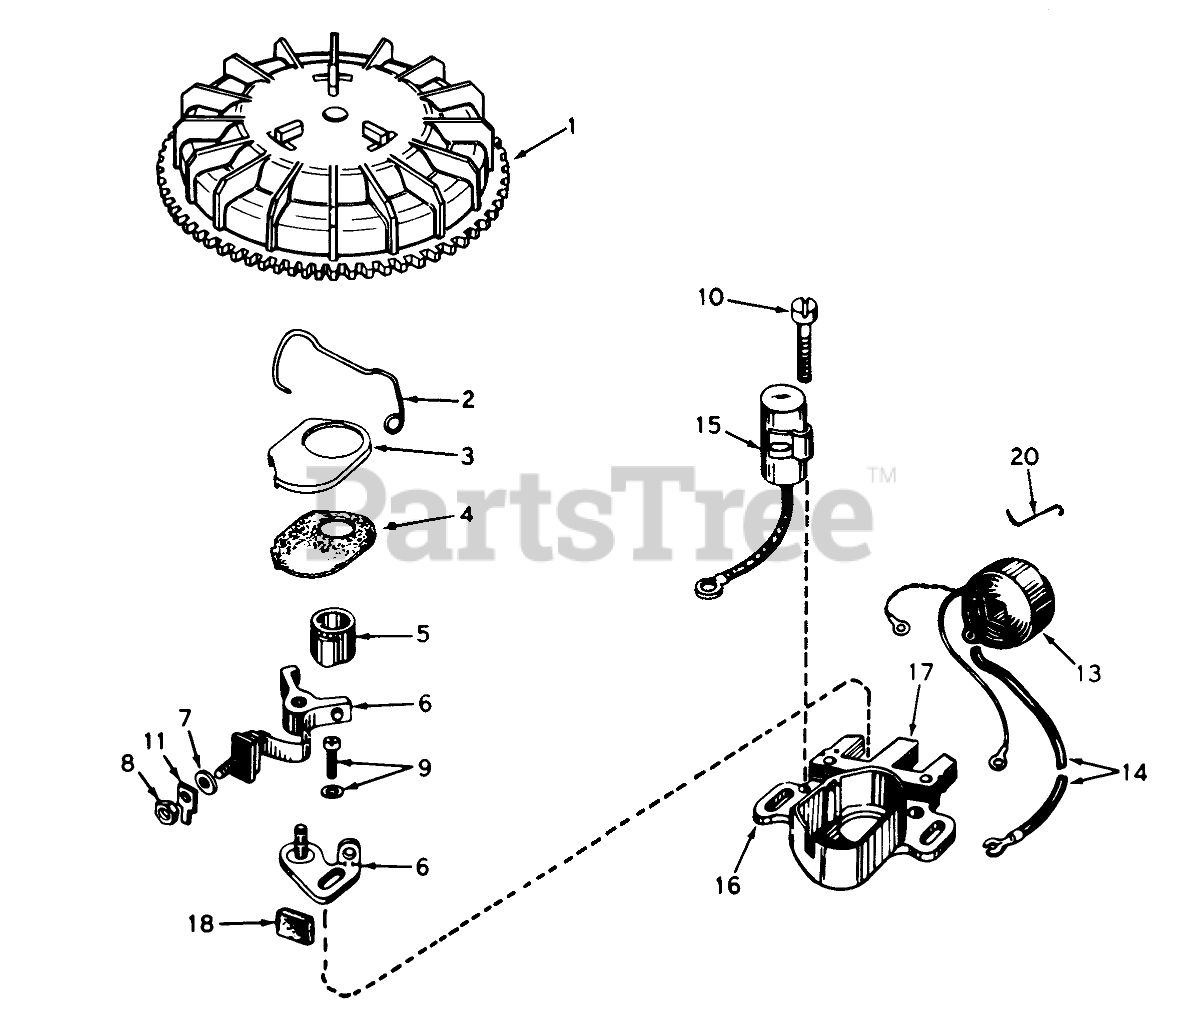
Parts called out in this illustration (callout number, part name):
1	Flywheel (Incl. Ref. #3 & 4)
2	Spring Breaker Box
3	Cover-Dust
4	Gasket, Dust Cover
5	Cam, Breaker
6	Breaker Assy.
9	Breaker Screw
10	Condenser Screw
11	Terminal, Ground
13	Coil Assembly (Incl. Ref. #14)
14	Wire, Lead
15	Condenser
16	Core & Plate
17	Stator Assembly (Incl. Ref. #2, 3, 4, 6 thru 16, 18 & 20)
18	Felt,Cam Wiper
20	Clip, Coil
